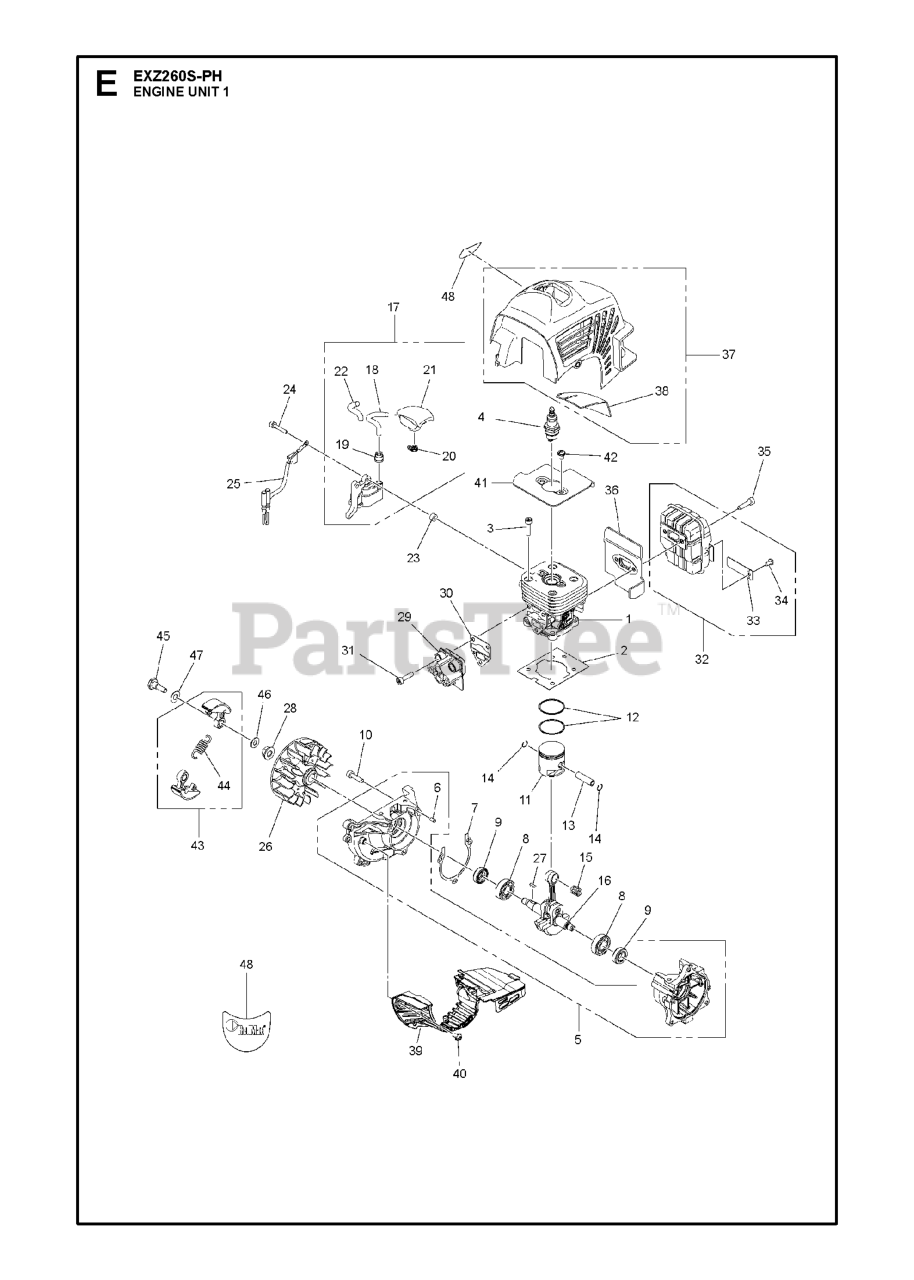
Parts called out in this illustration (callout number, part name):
1	CYLINDER COMP
2	GASKET BASE
4	SPARK PLUG, BPMR8Y
5	CRANKCASE ASSY
7	GASKET CASE
12	RING, PISTON
13	PIN
16	CRANKSHAFT COMP
17	IGNITION COIL,ASSY
18	IGNITION CABLE
19	HUB CAP 848F6L71E0
21	SPARK PLUG CAP
22	TUBE (RPLS 263072210)
24	BOLT M4 X 25
25	SHORT CIRCUIT CABLE
26	FLYWHEEL
27	KEY
28	NUT
29	INSULATOR
32	MUFFLER ASSY
33	SPARK ARRESTER
34	SCREW CRPANT TYPE F ST4.2X9.5
36	GASKET MUFFLER
37	CYLINDER COVER COMP
38	SHEET HEAT INSULATION
39	GUARD,COOLING AIR INTAKE
41	PLATE CYLINDER
43	CLUTCH ASSY
44	CLUTCH SPRING
48	DECAL BRAND
